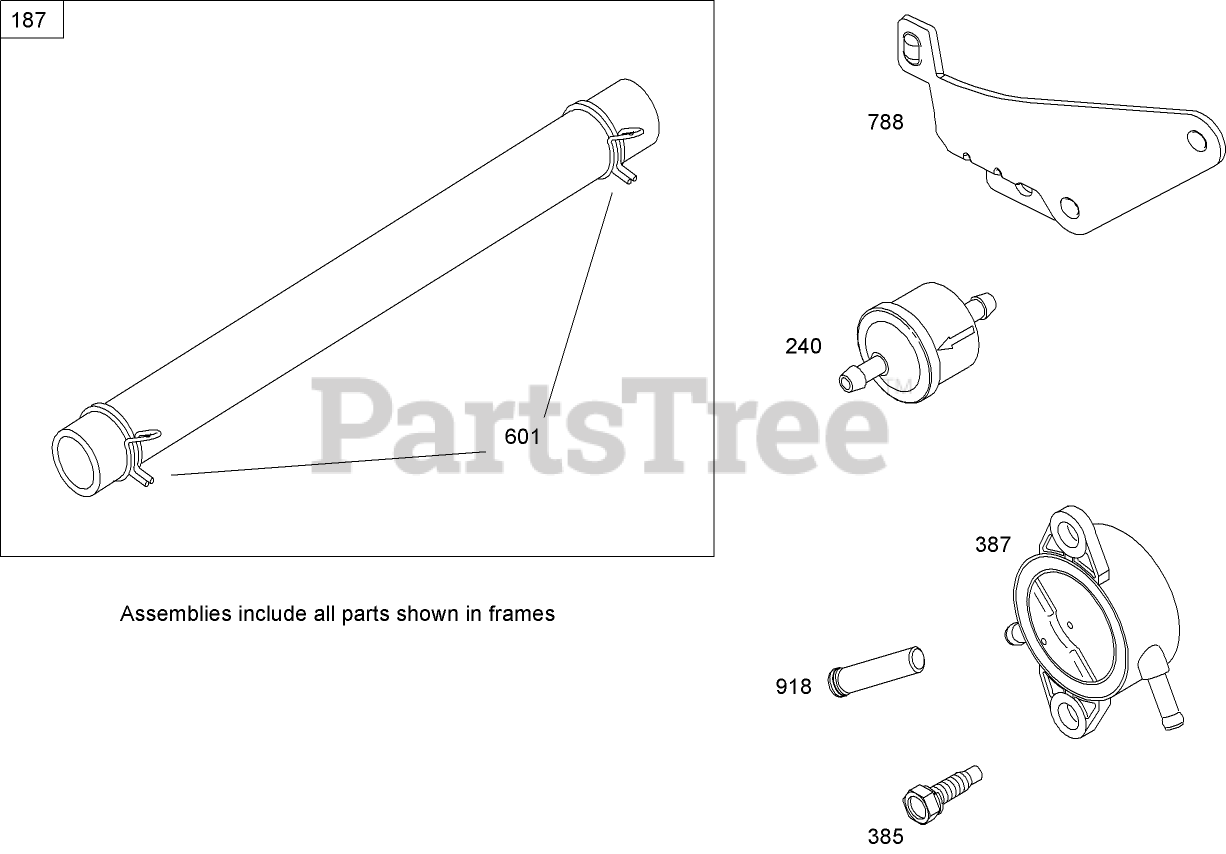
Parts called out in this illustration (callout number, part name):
187	Line-Fuel (Cut to required length)
240	Filter-Fuel
385	Screw
387	Pump-Fuel
601	Clamp-Hose
788	Bracket-Pump, Fuel
918	Hose-Vacuum
